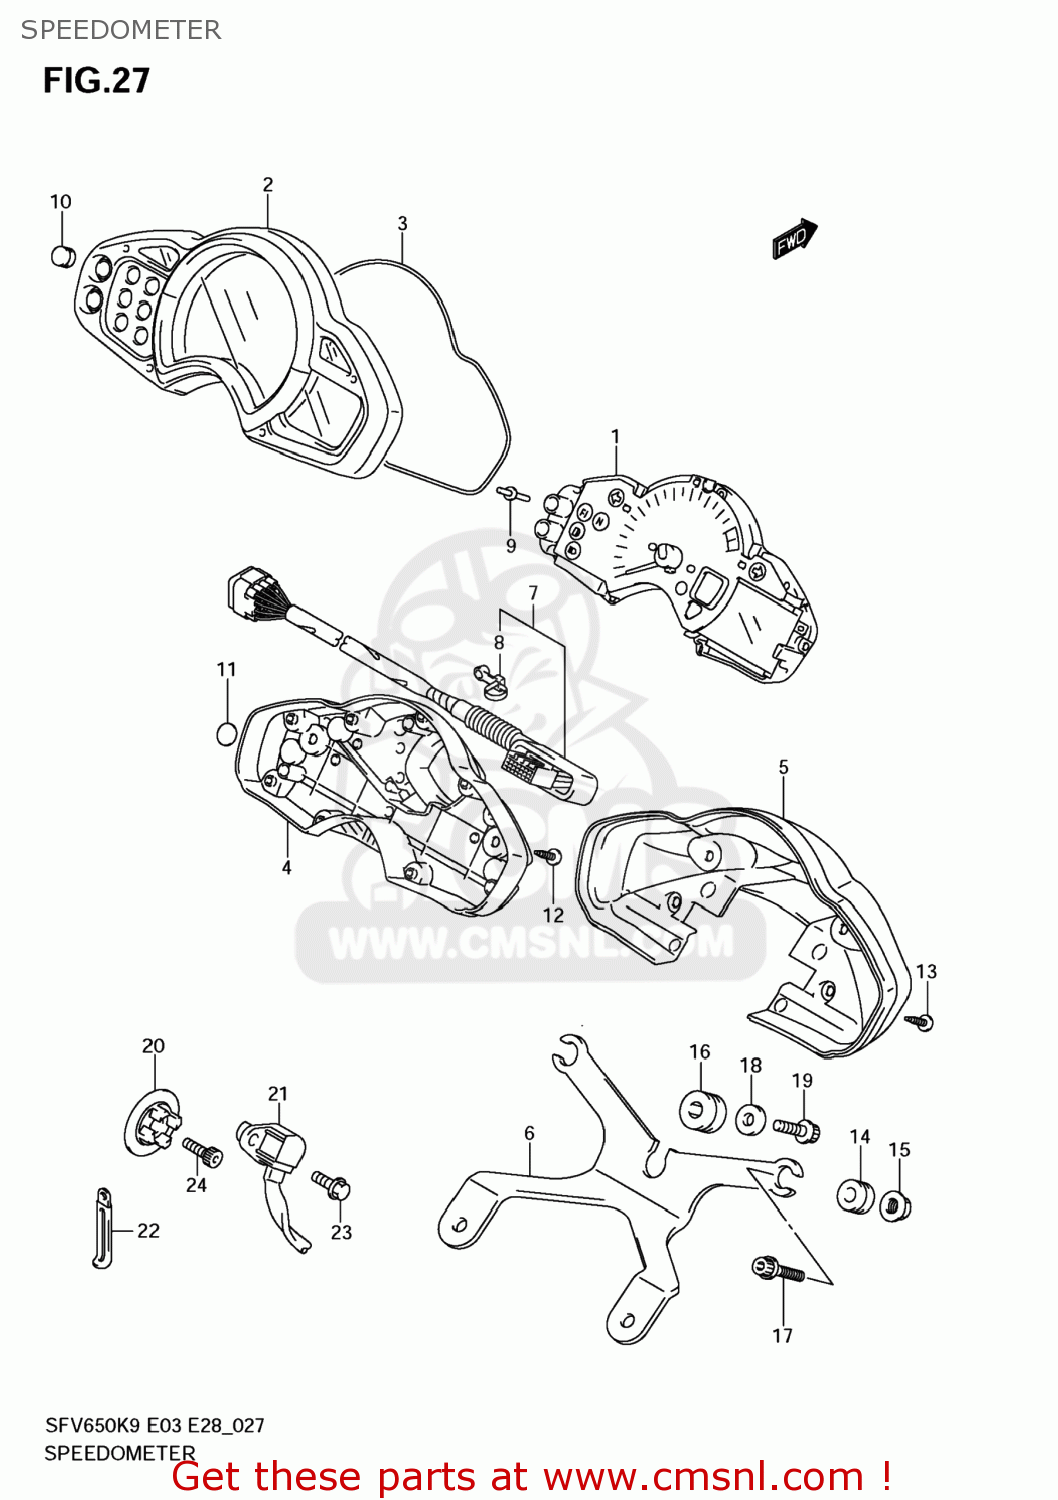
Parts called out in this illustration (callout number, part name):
1	SPEEDOMETER
2	CASE ASSY
3	PACKING RUBBER (NAS)
4	CASE
5	CASE,LWR
6	HOLDER CASE
7	WIRE,ASSY
8	CLAMP,LEAD WIRE
9	KNOB,SPEEDOMETER
10	COVER,SPEEDOMETER
11	SEAL
12	SCREW(3X12)
13	SCREW(4X14)
14	CUSHION,METER
15	NUT
16	CUSHION
17	SCREW,SPEEDOMETER
18	WASHER
19	BOLT
20	ROTOR,SPEED
21	SENSOR,SPEED
22	CLAMP(L:45)
23	BOLT
24	BOLT
